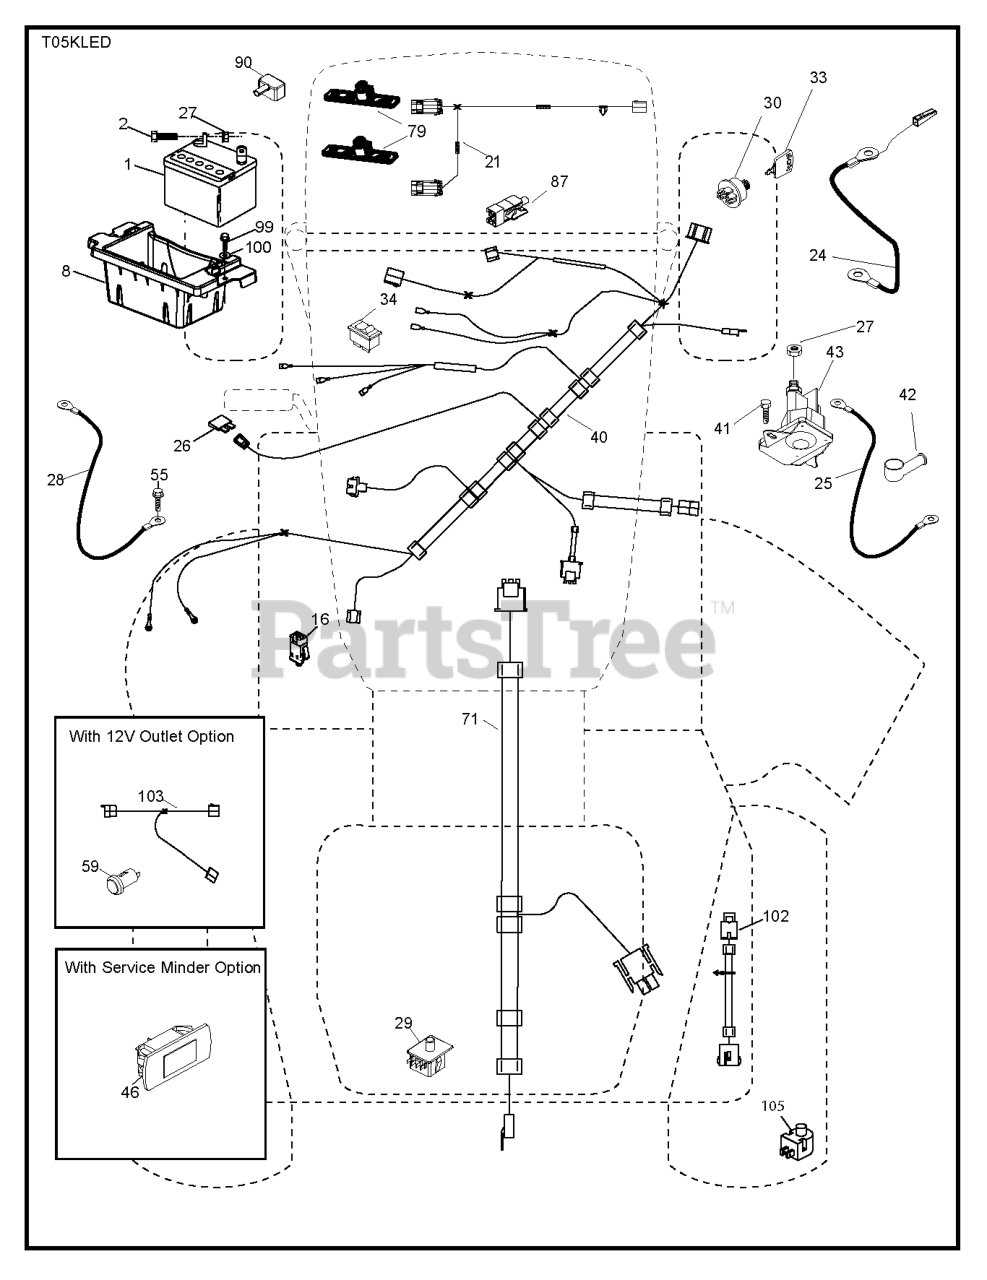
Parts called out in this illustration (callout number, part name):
1	Battery 12 Volt 25 Amp
2	BOLT.HEX.1/4.X.3/4.DICHROMATE
8	TRAY.ASM.BATTERY.FRT.TEX.CARB
8	TRAY.BATTERY BOX.FRONT
16	SWITCH INTERLOOK PUSH-IN
24	CABLE.FRBATT.W/WIRE.8GA.8
25	CABLE.STARTER.8GA.17.5
26	FUSE 20AMP
27	NUT
27	Hardware
28	CABLE.GROUND.21"BLK.8GA.90T
29	SWITCH.SEAT.DP W/RAMPS
30	SWITCH.IGN.DELTA.W.LGH.ROS
33	KEY.CHAIN.BLISTER.PACK.GEN.INT
40	HARNESS.IGN.DASH.CBL.YTGT.PRED
41	SCREW
42	TERMINAL COVER
43	SOLENOID.STARTER.BRASS.PLUNGER
43	Solenoids
46	GUAGE.SRVCMNDR.HRMTR.
55	SCREW 5/16"
71	HARNESS-CHASSIS SUB
87	SWITCH.INTRLCK.CLUTCH.
90	COVER.TERMINAL.BATTERY
99	SCREW HEXWSHR 1/4-20X3/4
102	HARNESS PIGTAIL PCH TEX ROS
105	REVERSE SWITCH
